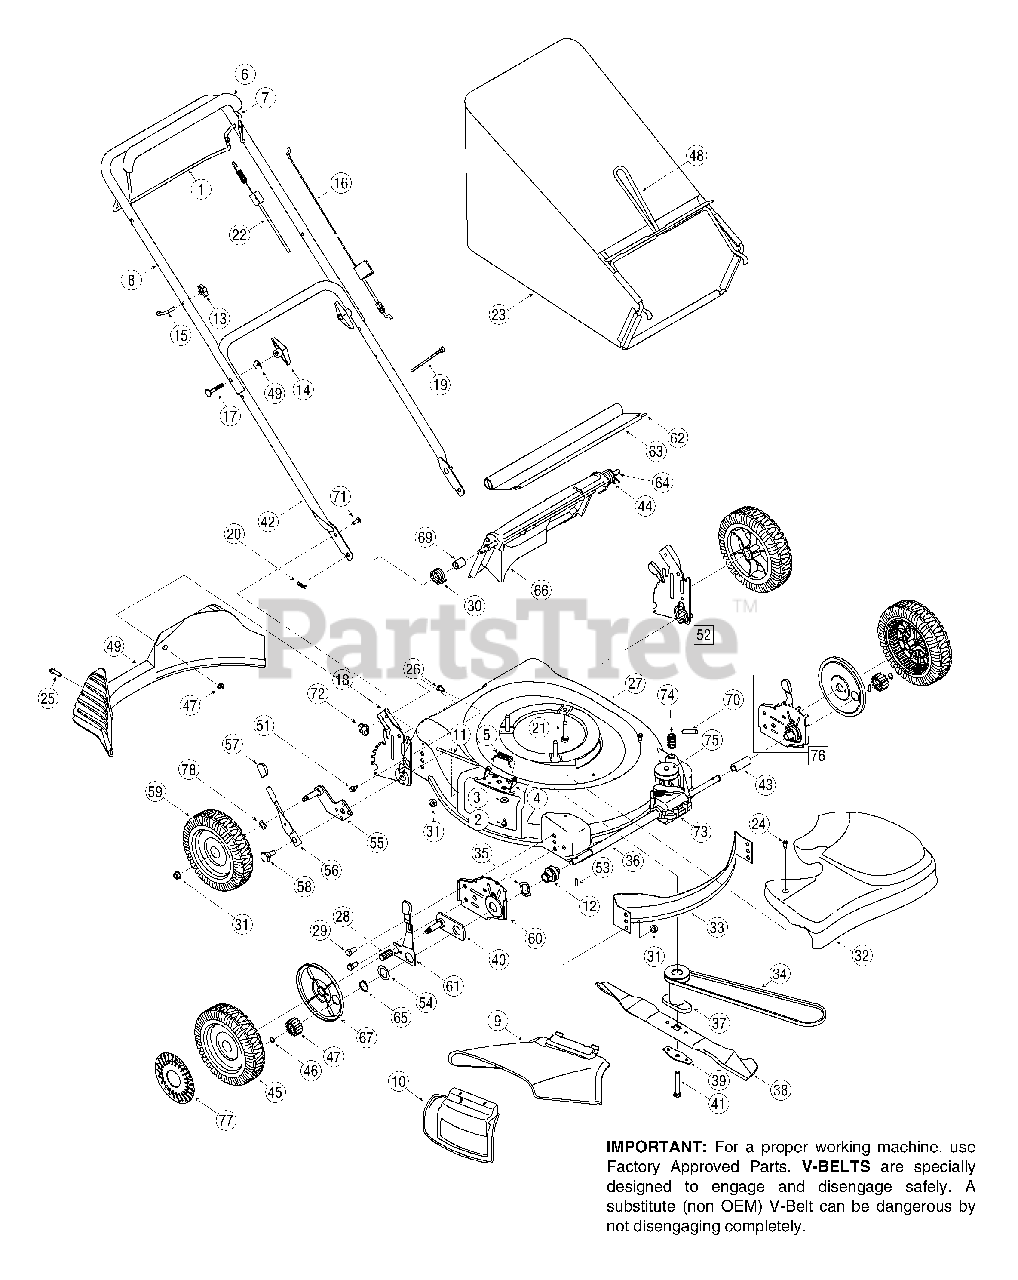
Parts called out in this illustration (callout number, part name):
1	Lower Bail Handle
2	TT Screw 1/4-20 x 0.5
3	Bell Washer.265 x 0.75
4	Deflector Chute Adapter
5	Torsion Spring
6	Snap-On Bail Cover
9	Chute Deflector
10	Mulch Plug Complete
11	Hinge Pin
12	Bearing Assembly
16	Control Cable - 50.56"
17	Carriage Bolt 5/16-18 x 2.0
18	RH Handle Bracket
19	Cable Tie
21	Self-Tapping Sems Screw
22	Drive Cable
23	Grassbag Assembly
24	Shoulder Screw # 12 -24
25	Machnined Screw 1/4-20
26	Hex Lock Screw 1/4-15
29	Hex Screw 3/8-16 x.75
30	Torsion Spring RH
31	Flange Lock Nut 3/8-16
32	Transmission Cover (Gray)
33	Front Baffle
34	V-Belt
36	Sleeve Spacer 9.04" Lg.
37	Blade Adapter w/ Pulley
38	21" Mulching Blade
39	Blade Bell Support
40	Pivot Plate Assembly
41	Hex Screw 3/8-24 x 2.50
43	Slev. Spacer 2.1" Lg.
44	Torsion Spring LH
45	Front Wheel 8x2.125 Gear Gray
47	Gear 14T RH FWD
49	Saddle Washer
50	Hex Screw 1/4-20 x 1.50
51	TT Scr. w/Washer 1/4-20 x.625
52	RH Handle Bracket Assembly
53	Dowel Pin
55	Pivot Arm Assembly - RH
56	Rear Spring Lever
57	Spring Lever Knob
58	Shoulder Scr.500 Dia. x.434
59	Rear Wheel 8x2.125 Gray
62	Wire
64	Pivot Rod
66	Rear Discharge Door
67	Wheel Dust Cap
68	Flange Lock Nut 1/4-20
69	Spacer.375 x.50 x 1.02" Lg.
71	Carriage Bolt 1/4-20
72	Wing Nut
73	Transmission Assembly
74	Belt Tension Spring
76	Height Adjustment Assembly RH
77	Hub Cap - Radial Spoke Gray
78	Wave Washer .510 x .750 x .017
